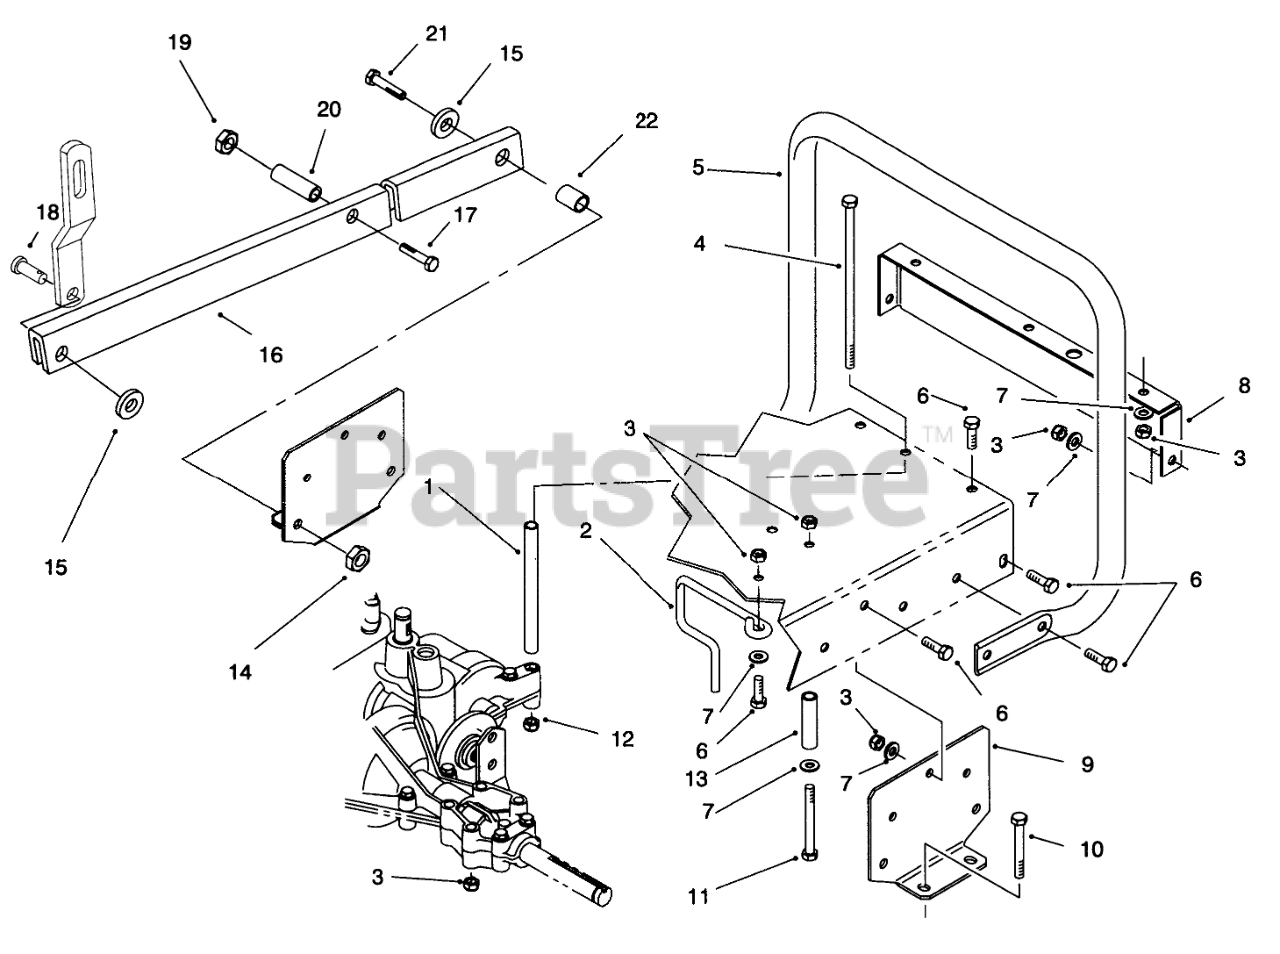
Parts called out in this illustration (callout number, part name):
1	SPACER-TRANSAXLE SUPT
2	GUIDE-ENG BELT
3	NUT-LOCK, NI
4	SCREW-HH
5	Standbar
6	SCREW-HH
7	WASHER-PLAIN
8	Frame-Rear
9	Support-Axle
10	SCREW-HH
11	SCREW-HH
12	NUT-LOCK, NI
13	SPACER-SPLIT TUBE
14	NUT-LOCK, NI
15	WASHER-FLAT
16	Arm-Suspension R.H.
17	SCREW-HH
18	PIN-CLEVIS
19	NUT-LOCK, NI
20	SPACER-SPLIT TUBE
21	SCREW-HH
22	PIN-SUPT ARM
